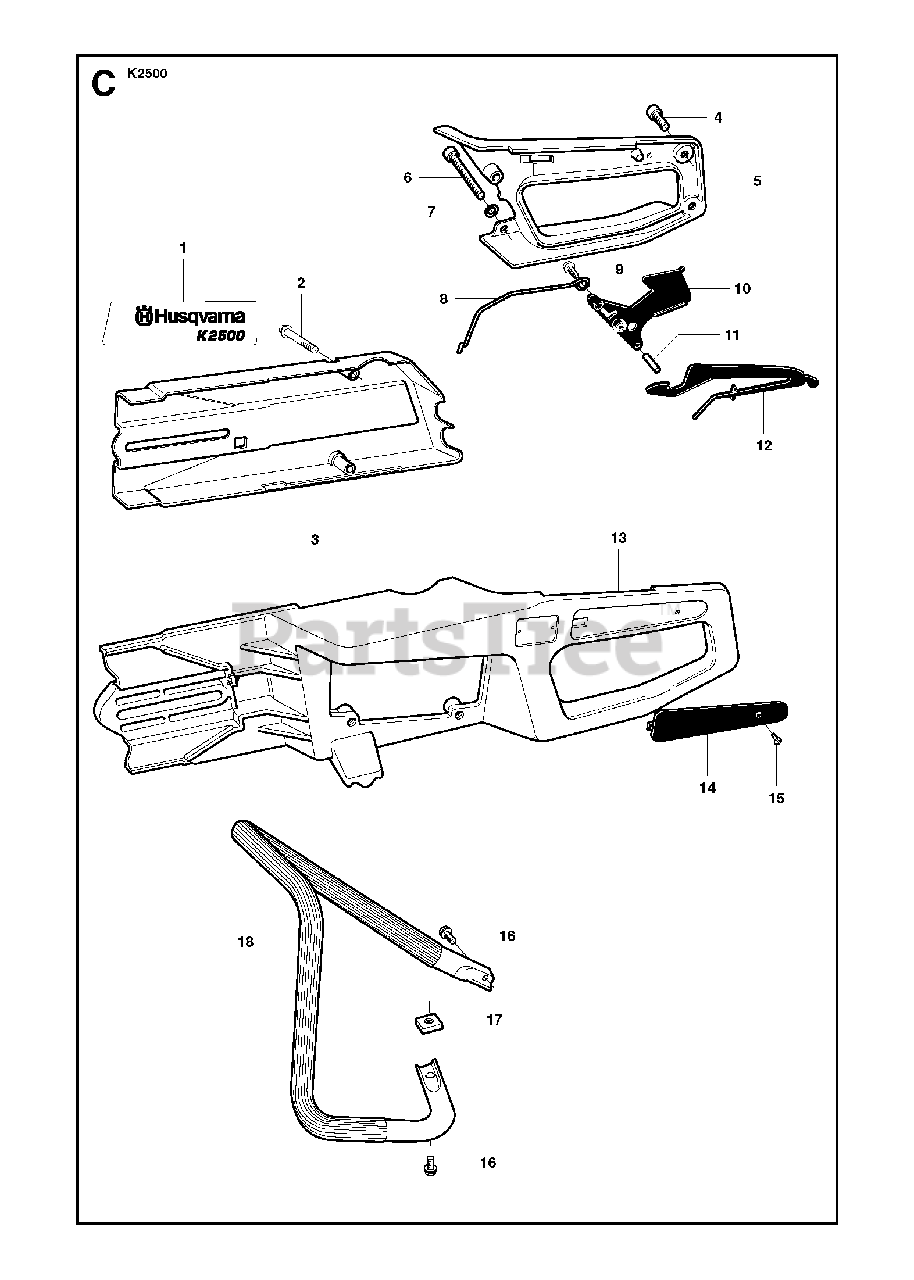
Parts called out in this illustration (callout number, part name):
2	SCREW IHSCFM
9	SCREW CCRPANT
11	PARALLEL PIN
12	THROTTLE LOCKOUT
14	HANDLE INSERT
16	SCREW IHSCFM
